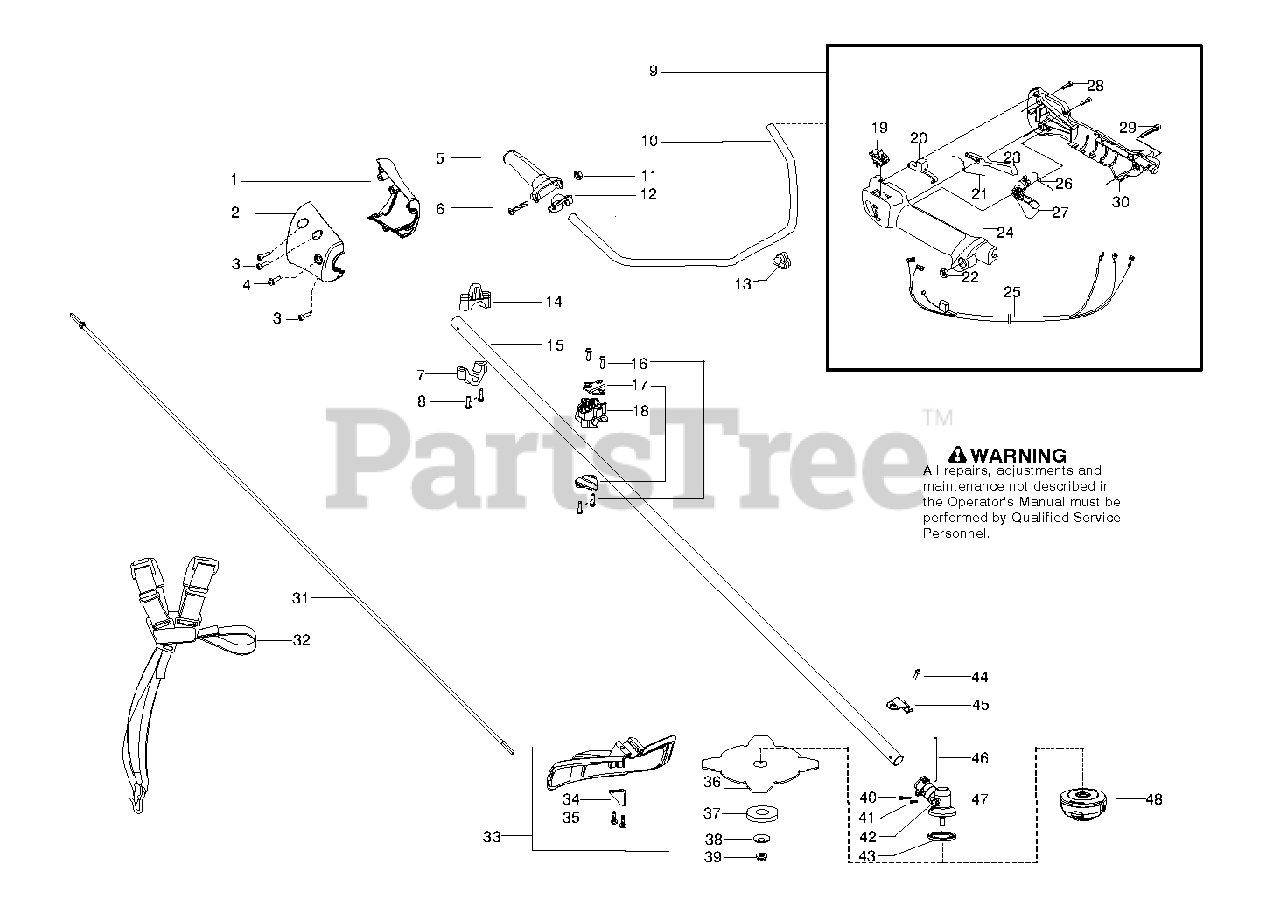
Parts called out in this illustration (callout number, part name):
3	SCREW M4 X 1.75 PT 16MM
4	SCREW-10-16 X 1/2, TYPE 2
7	CLAMP HARNESS LOWER
14	CLAMP HARNESS UPPER
17	CLAMP BRACKET
19	STOP BUTTON
20	STARTER THROTTLE LOC
25	ASSY CABLE WIRE HARNESS
29	%SCREW
31	FLEXSHAFT 57"
33	KIT SHIELD
34	LINE CUTTER
36	BLADE GRASS
37	SUPPORTING CUP
38	SUPPORT FLANGE
39	GEARHEAD NUT - BRUSHCUTTER
40	SCREW - CARB. ADAPTOR
43	DRIVE DISC
44	SCREW 1/4-20 X 7/8 (TAP
45	BRACKET SHIELD STRAIGHT SHAFT
46	LOCKING PIN
47	ASSY GEARBOX
48	T25 TRIM HEAD 10MM LH
